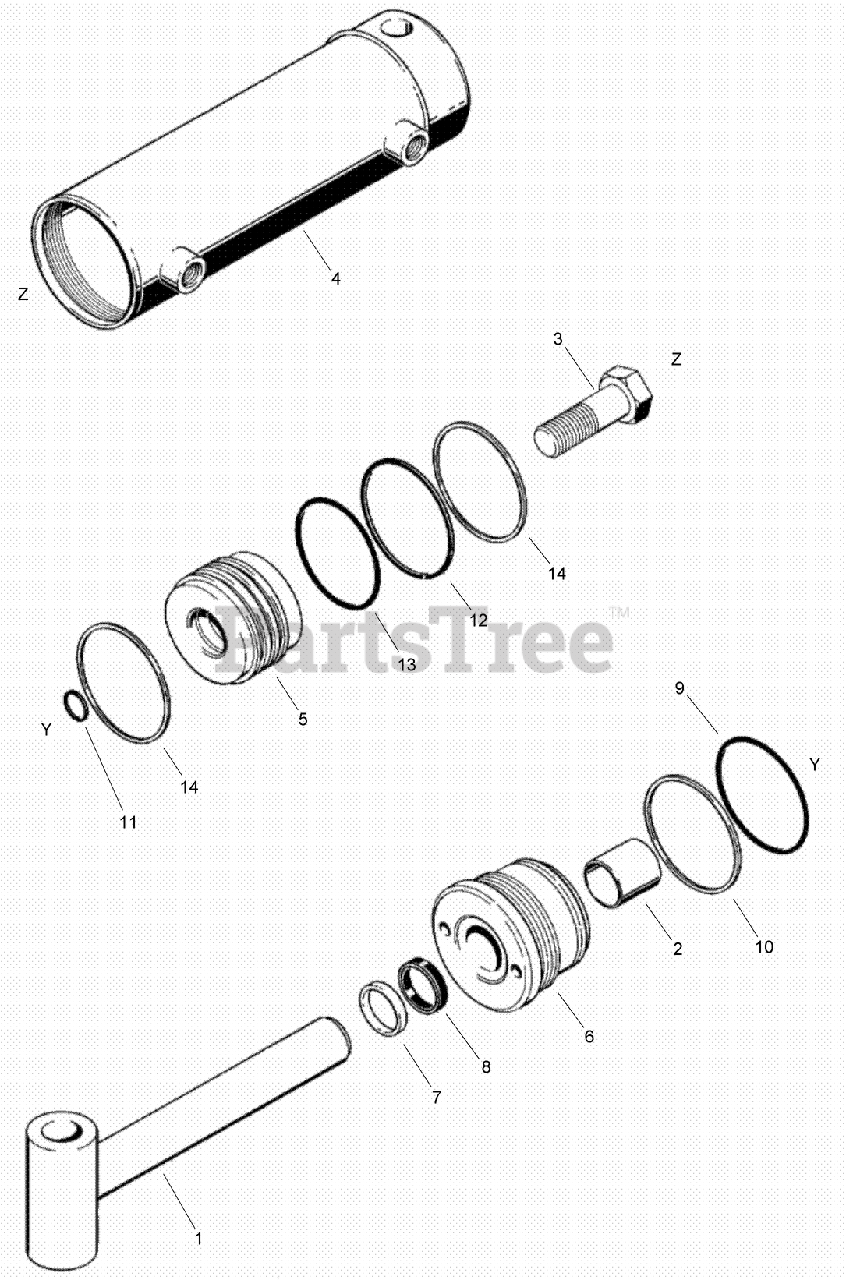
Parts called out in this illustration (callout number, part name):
2	BUSHING
3	CAPSCREW, 3/8 NF x 2-1/2, GR8
7	WIPER-piston rod
8	Seal-U-Cup
9	O-RING-gland
10	RING-Backup, Gland
11	O-RING-piston rod
12	Piston Seal
13	O-RING-piston
14	WEAR RING
